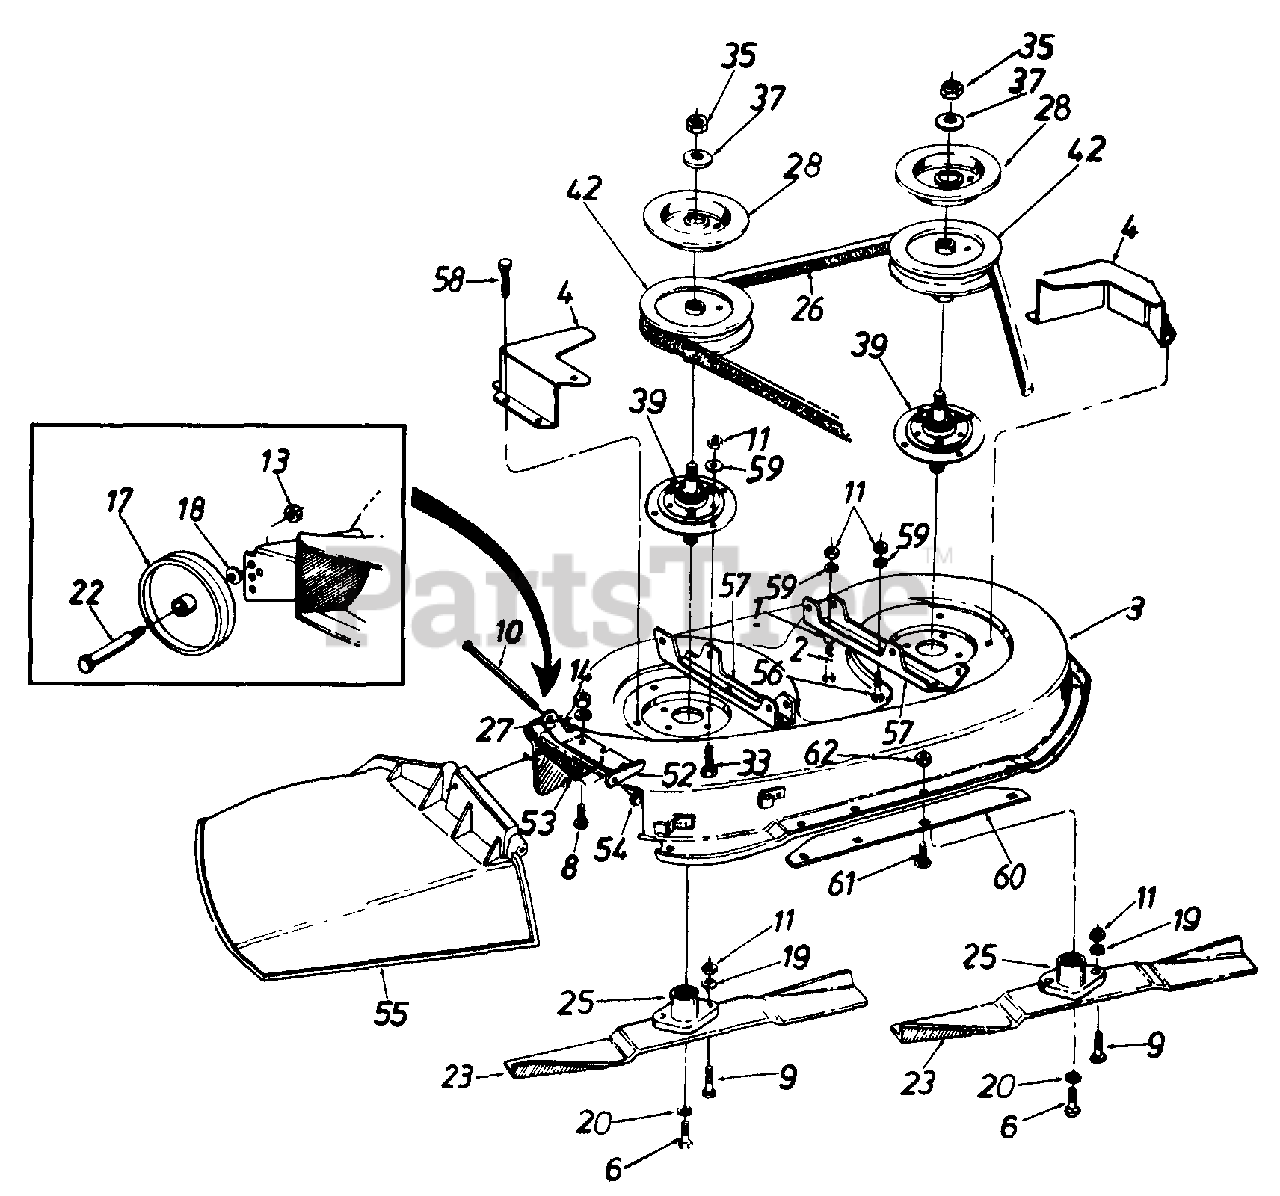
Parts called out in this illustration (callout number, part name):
1	Spacer .33" I D. x .88"
2	Hex Bolt 5/16-24 x 1.25" Lg.
6	Hex Bolt 3/8-24 x 1.0" Lg.
8	Hex Bolt 1/4-20 x .62"
9	Hex Bolt Special 5/16-24 x 1.0"
10	Hinge Pin
11	Hex Nut 5/16-24 Thd.
13	Hex Top L-Nut 3/8-16 Thd.
14	Hex Nut 1/4-20 Thd.
17	Deck Wheel - 5"
18	Bell-Wash .40" I.D. x .88" O.D.
19	L-Wash. 5/16" I.D.
20	L-Wash. 3/8" I.D.- H.D.
22	Shld. Bolt .498" Dia. x 1.53"
23	High-Lift Blade
25	Blade Adapter
26	V-Belt
27	Bell-Wash. 1/4" I.D.
28	Brake Disc
33	Hex Bolt 5/16-24 x .75" Lg.
35	Hex Jam Nut 5/8-18 Thd.
37	L-Wash. 5/8" I.D.
39	Blade Spindle Ass'y. Comp.
42	5" Dia. Pulley
52	Hinge Mtg. Brkt.
53	Torsion Spring
54	Push Nut
55	Chute Ass'y. Comp.
56	Hex Bolt 5/16-24 x .75" Lg.
59	Bell-Wash .345" I.D. x .88"
62	Hex Sems Nut 1/4-20 Thd.
